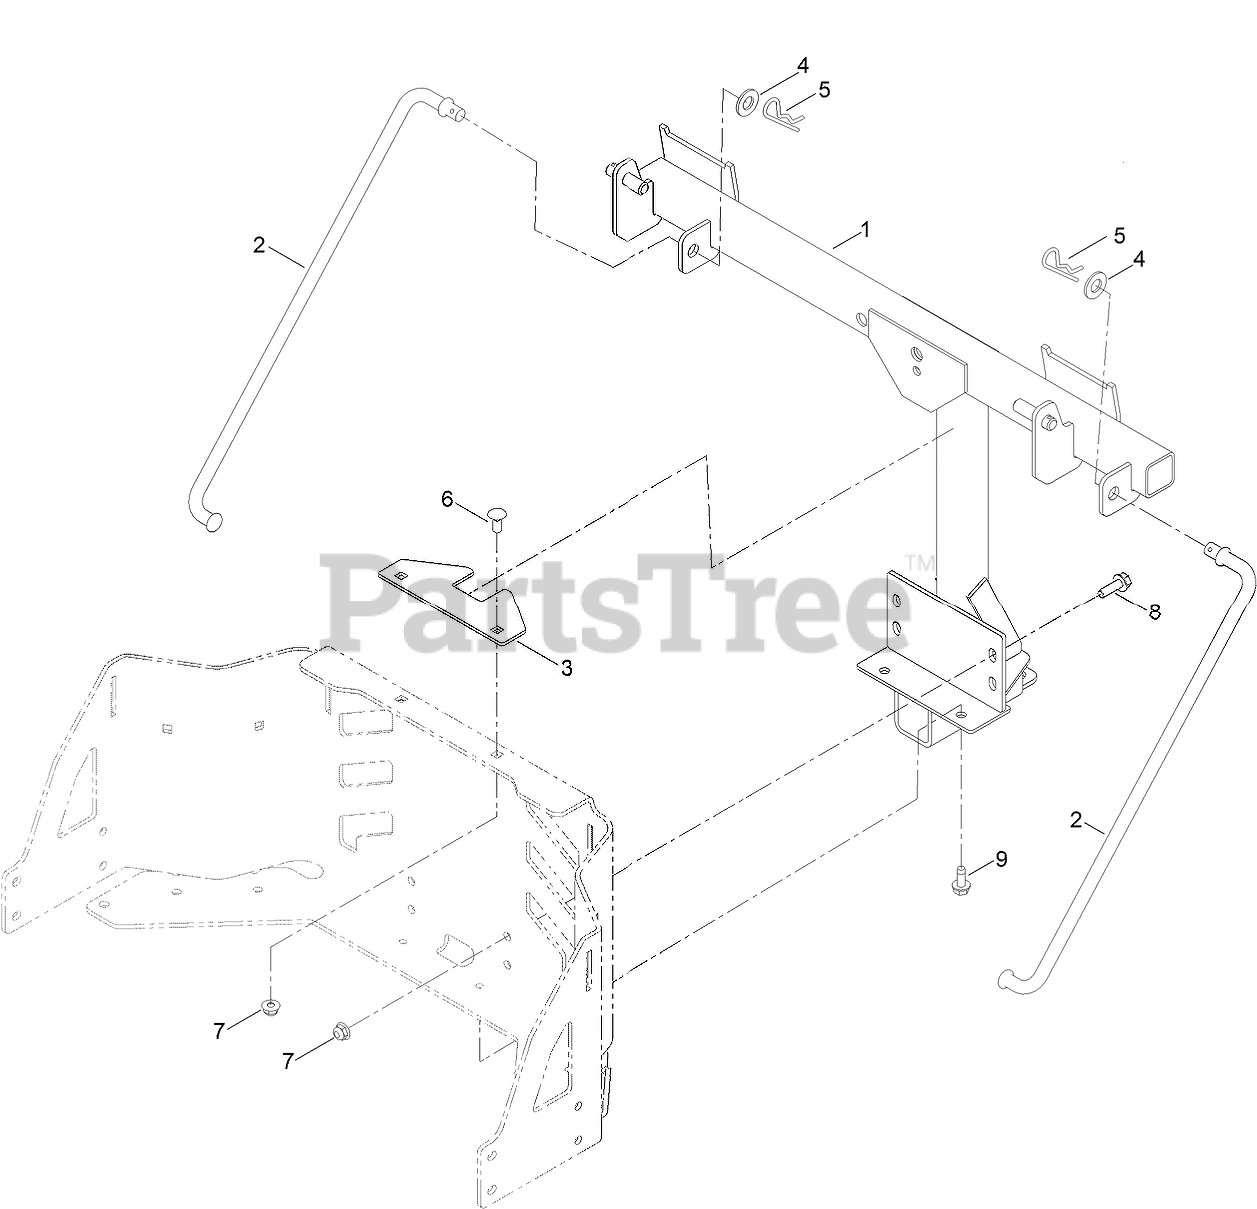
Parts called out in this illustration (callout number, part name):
1	FRAME-PIVOT
2	ROD-SUPPORT
3	SUPPORT-UPPER
4	WASHER-FLAT
5	PIN-HAIR
6	BOLT-CARR
7	NUT-HF
8	SCREW-HHF
9	SCREW-HWHTF
